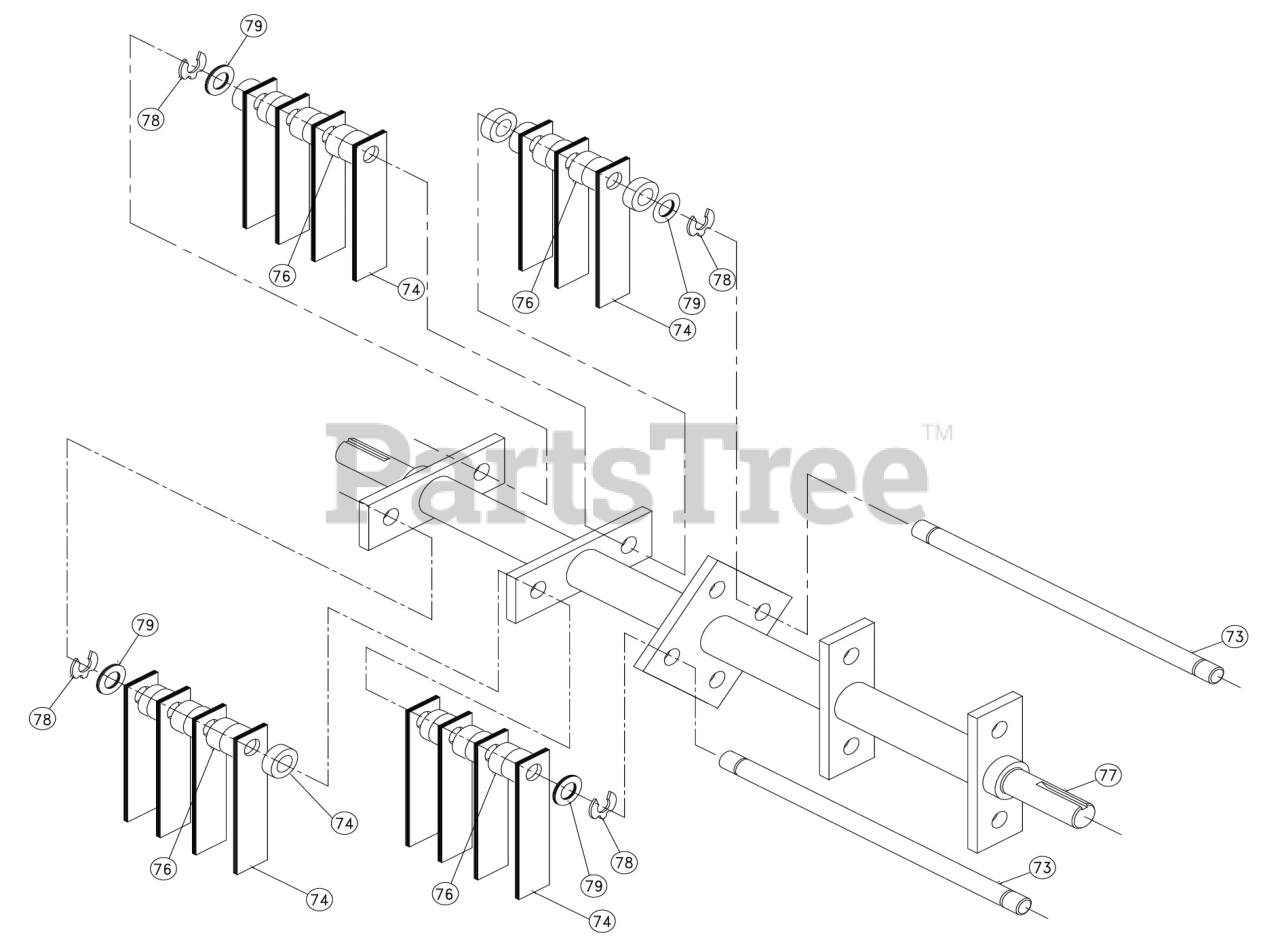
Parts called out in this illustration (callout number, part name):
73	SHAFT FLAIL BLADE
74	BLADE FLAIL CR
76	SPACER BUMPER 5/8" X 1/2"
77	SHAFT FLAIL REEL
78	RING RETAINING 1/2"
79	WASHER 1/2" SAE Z/P
